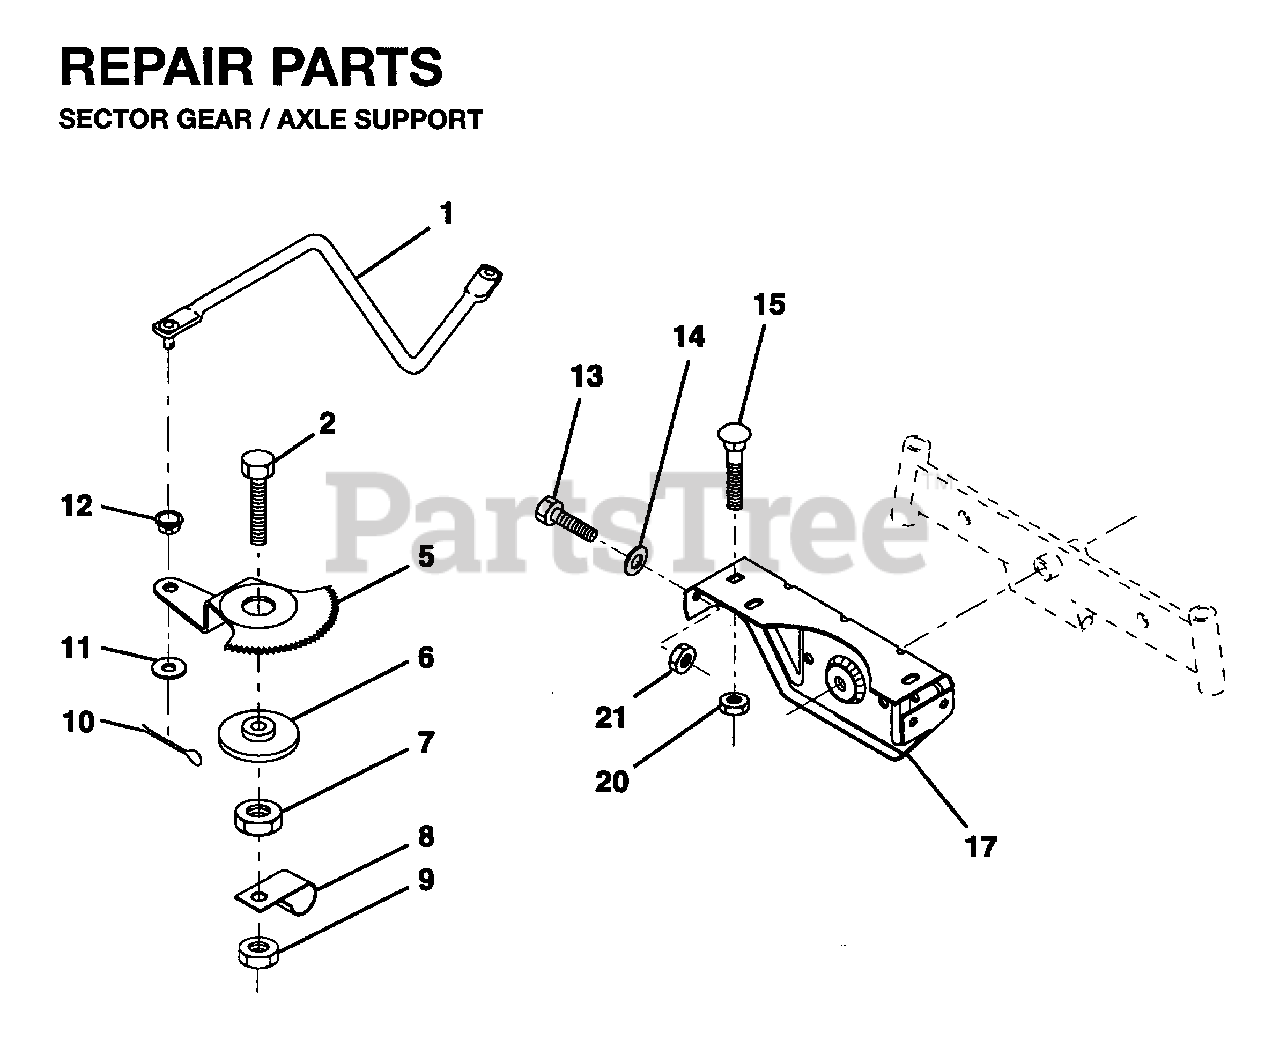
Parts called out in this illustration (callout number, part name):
1	LINK DRAG
5	GEAR SECTOR
7	NUT LTV
8	CLIP INSULATOR
9	NUT LTV
10	COTTER PIN
11	WASHER
12	BUSHING.DRAGLINK
13	BOLT
14	WASHER - 25X8.5X2.3
17	SUPPORT/AXLE FRONT
20	LOCKNUT
21	NUT.71038.31-18.HEX.NYLOCK
